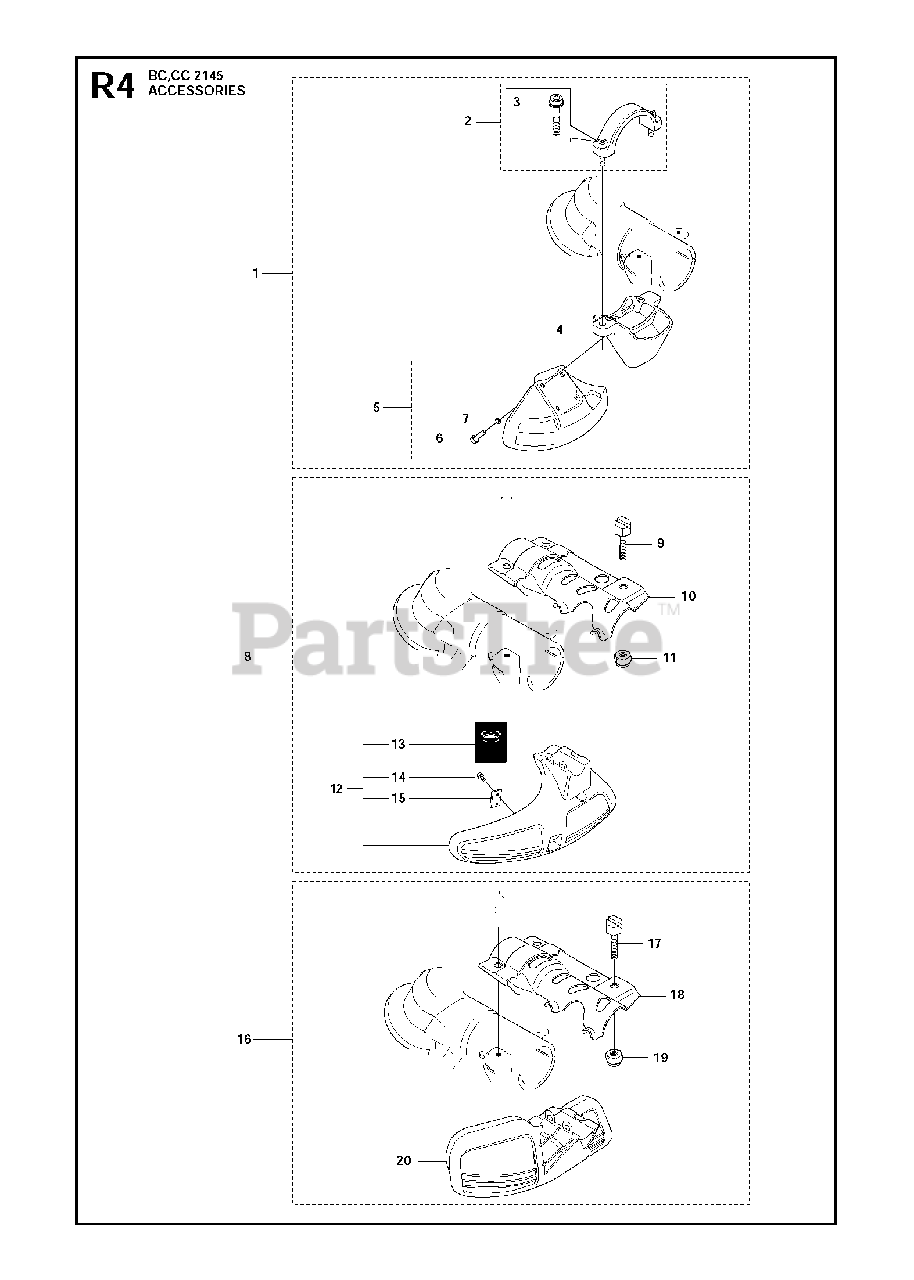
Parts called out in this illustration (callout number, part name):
1	TRIMMER GUARD ASSY
4	ADAPTER
5	RP BLADE GUARD
6	SCREW
8	SPLASH GUARD KIT
9	SCREW
10	PLATE
11	LOCKNUT M6
13	DECAL
14	SCREW
15	BLADE
16	TRIMMER GUARD ASSY
17	SCREW
18	PLATE
19	LOCKNUT M6
20	PROTCTOR
